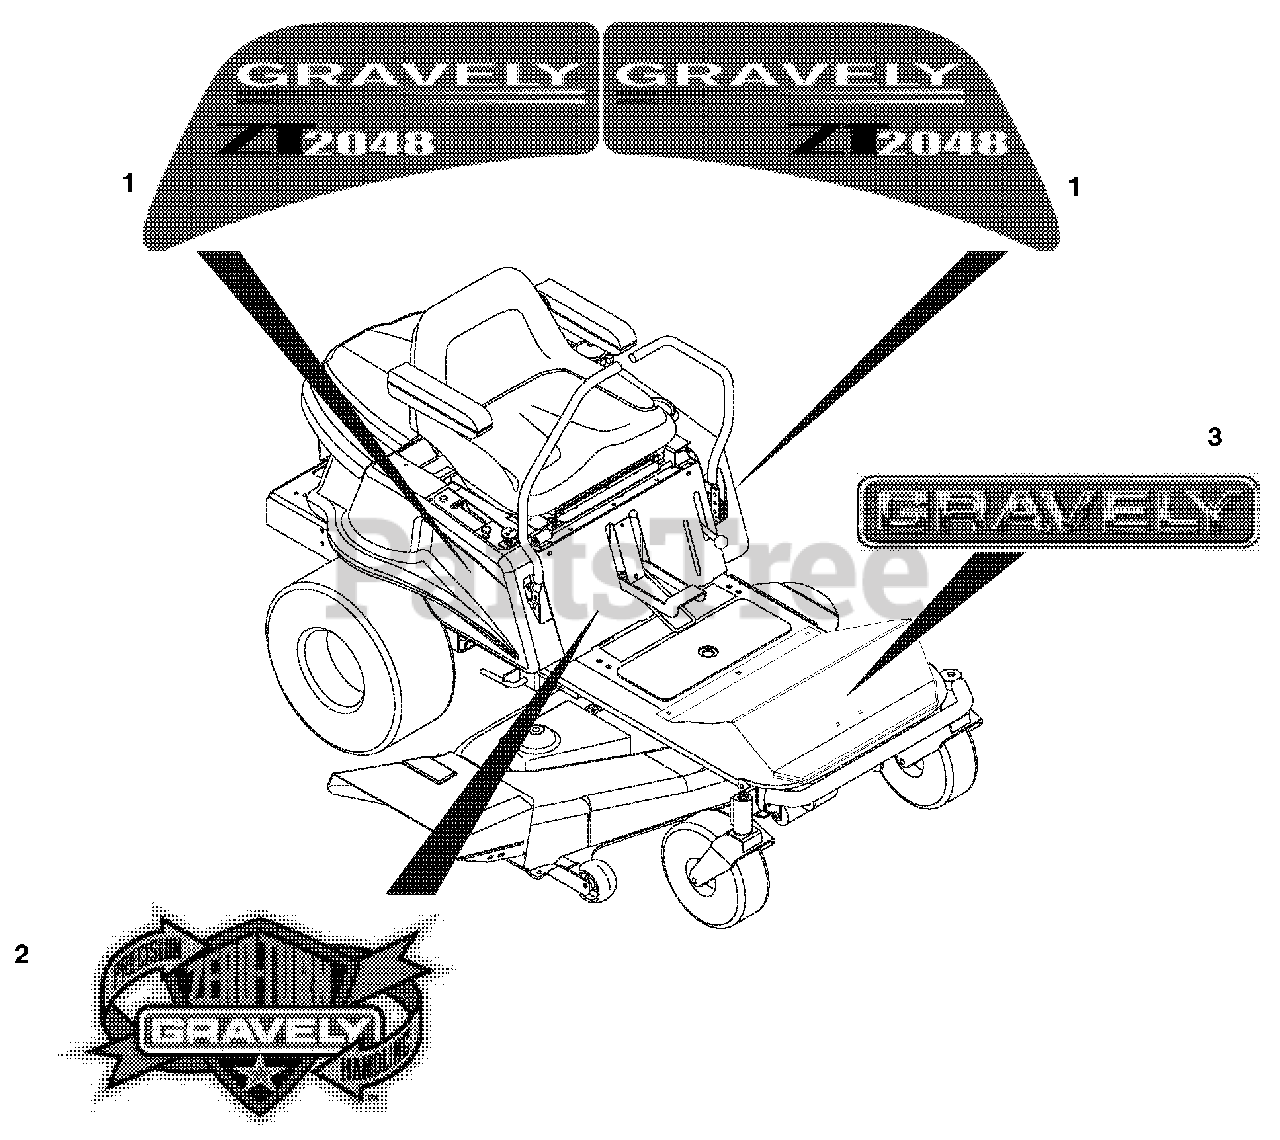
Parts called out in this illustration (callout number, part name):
1	Decal, Set ZT 2048
1	Decal, Set ZT 1842
1	Decal, Set ZT 1740
2	Decal, Zero Turn
3	Decal, Gravely Logo
